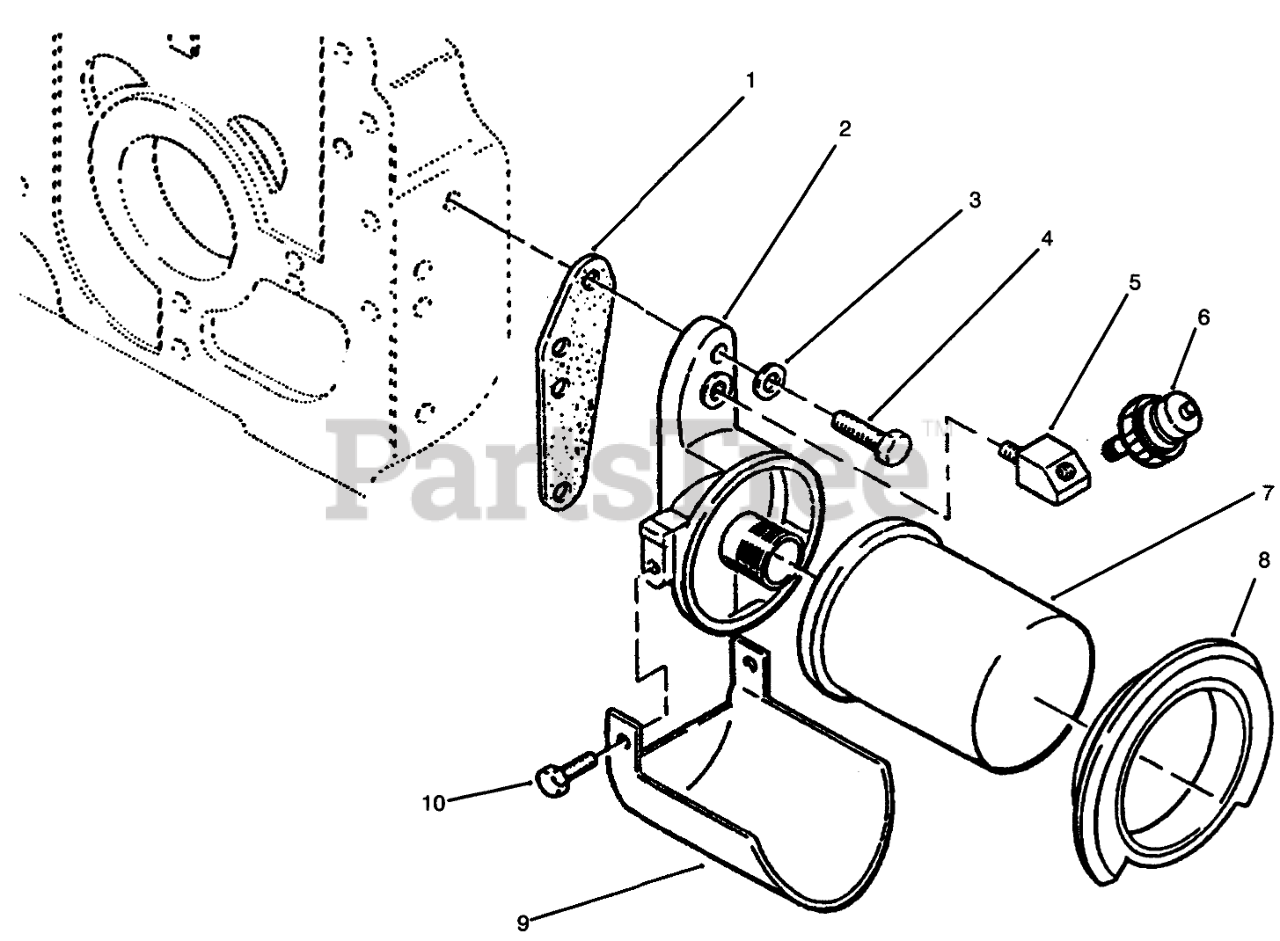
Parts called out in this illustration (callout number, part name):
1	Gasket
2	ADAPTER-OIL FILTER
3	WASHER
4	HHCS 5/16-18 X 1
5	45 DEG STREET ELBOW
6	SWITCH
7	OIL FILTER
8	GASKET - AIR SEAL
9	OIL-FILTER DRAIN
10	SCREW-HH
